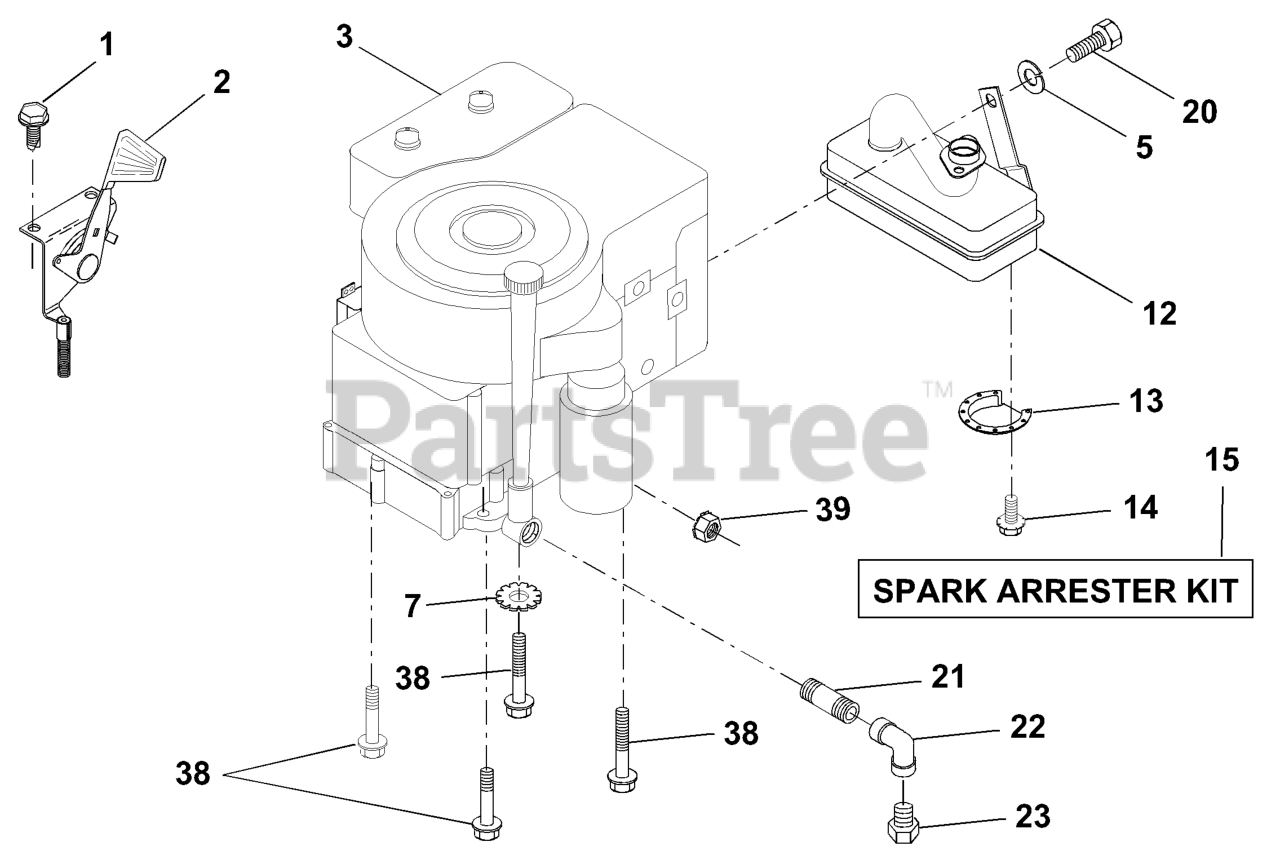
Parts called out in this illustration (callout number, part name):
2	THROTTLE CONTROL
3	Engine, Kohler, 12.5 HP
5	WASHER.LOCK.HVY.HLCL.SPR.5/16
7	LOCKWASHER
12	MUFFLER KOH
13	DEFL MUFFLER LTV
14	SCREW
15	KIT.SPARK ARRESTOR 794945 B&S
20	Bolt, Hex, Fin. 5/16 - 18 x 1/2
21	Nipple Pipe
22	ELBOW
23	Oil Drain Plug
38	BOLT, HEX
39	NUT FLANGE 1/4-20 STARTER NUT
